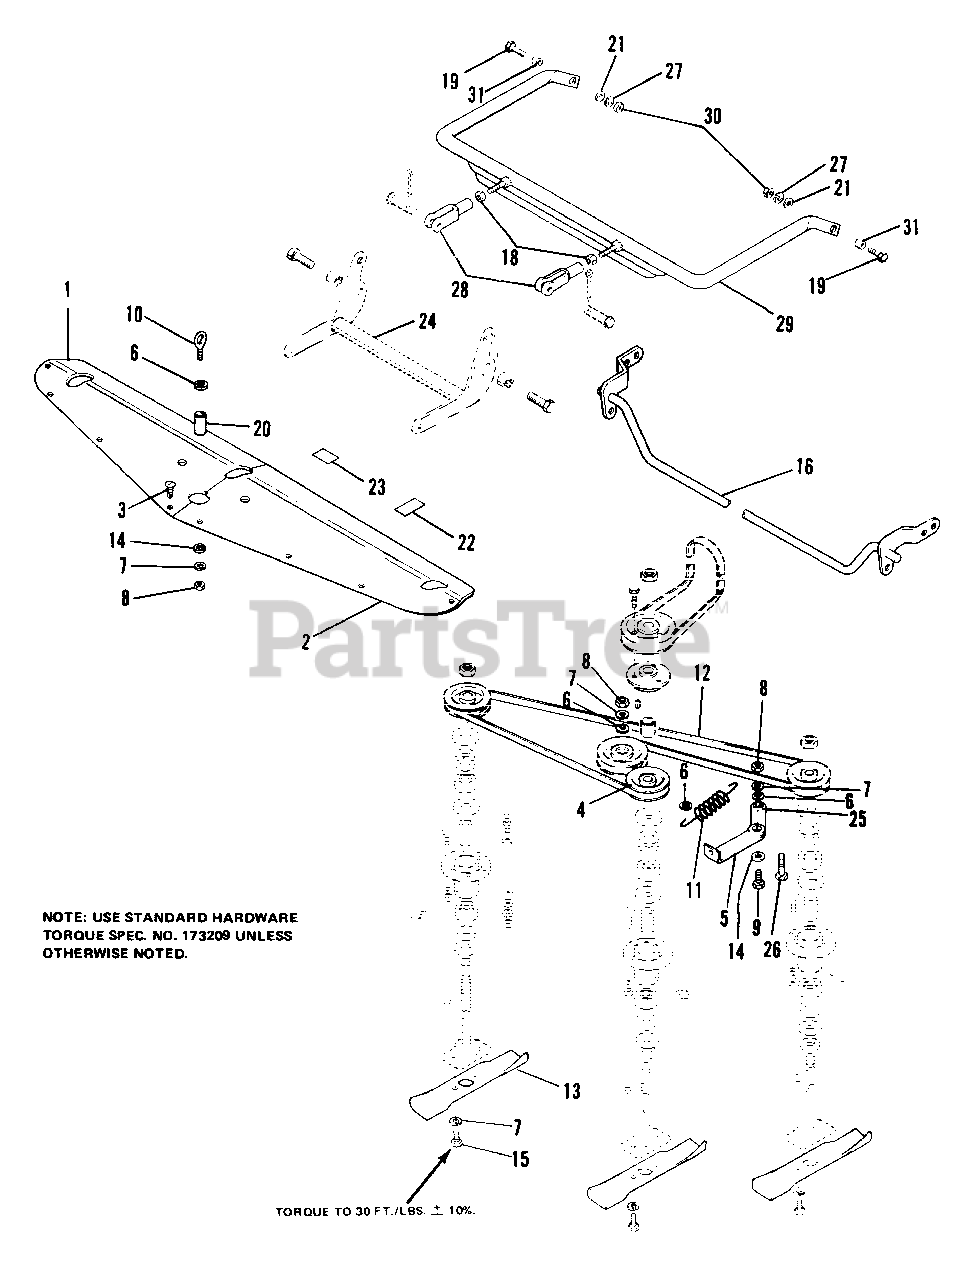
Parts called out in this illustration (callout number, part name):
1	COVER, R.H.
2	COVER, L.H.
3	SCREW, Hex,Taptite, 1/4-20 x 3/8
4	PULLEY, Idler
5	LEVER ASSY, Idler
6	WASHER, Plain, 5/16
7	LOCKWASHER, Spring, 3/8
8	NUT, Hex, 3/8-16
11	SPRING Tension
12	BELT, "V", Mower Drive
13	BLADE, Knife
14	WASHER, Plain, 3/8
15	CAPSCREW, Hex Hd., 3/8-16 x 5/8
16	ARM ASSY, Rocker
18	NUT, Hex, Jam, 1/2-20
19	CAPSCREW, Hex Hd., 1/2-13 x 1-1/4
21	WASHER, Plain, 7/16
22	FILM, Safety
23	FILM, Belt Installation
24	ARM ASSY, Rocker
25	RACE, Inner
26	CAPSCREW, Hex Hd, 3/8-16 x 1-3/4
27	LOCKWASHER, Spring, 1/2
28	YOKE, End Adj.
30	NUT, Hex, 1/2-13
